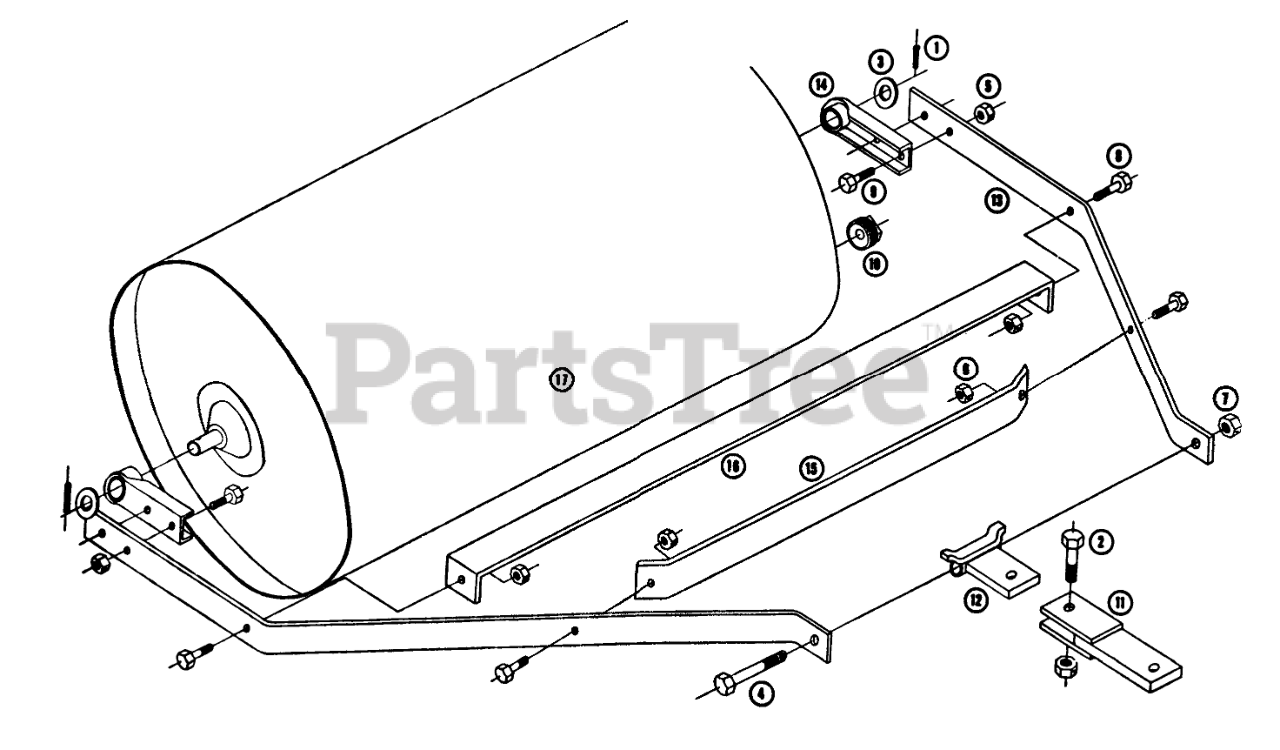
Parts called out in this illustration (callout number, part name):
1	Cotterpin 3/16 x 1 1/2
2	Bolt-1/2-13-1 3/4
3	Flat Washer 1" I.D.
4	Hex Hd. Cap Screw 1/2-13 x 3 1/4
5	Nut-Nylok
7	Nut-ES 1/2-13
8	Bolt 3/8-16 x 1
9	Bolt 1/4-20 X 3/4
10	1" Cast Bronze Pipe Plug
11	Hitch Bar W/A
12	Swivel Assembly
13	Frame Side Bar
14	Axle Pivot Tube
15	Frame Support
16	Scraper Bar
17	Tank W/A
18	Decal
